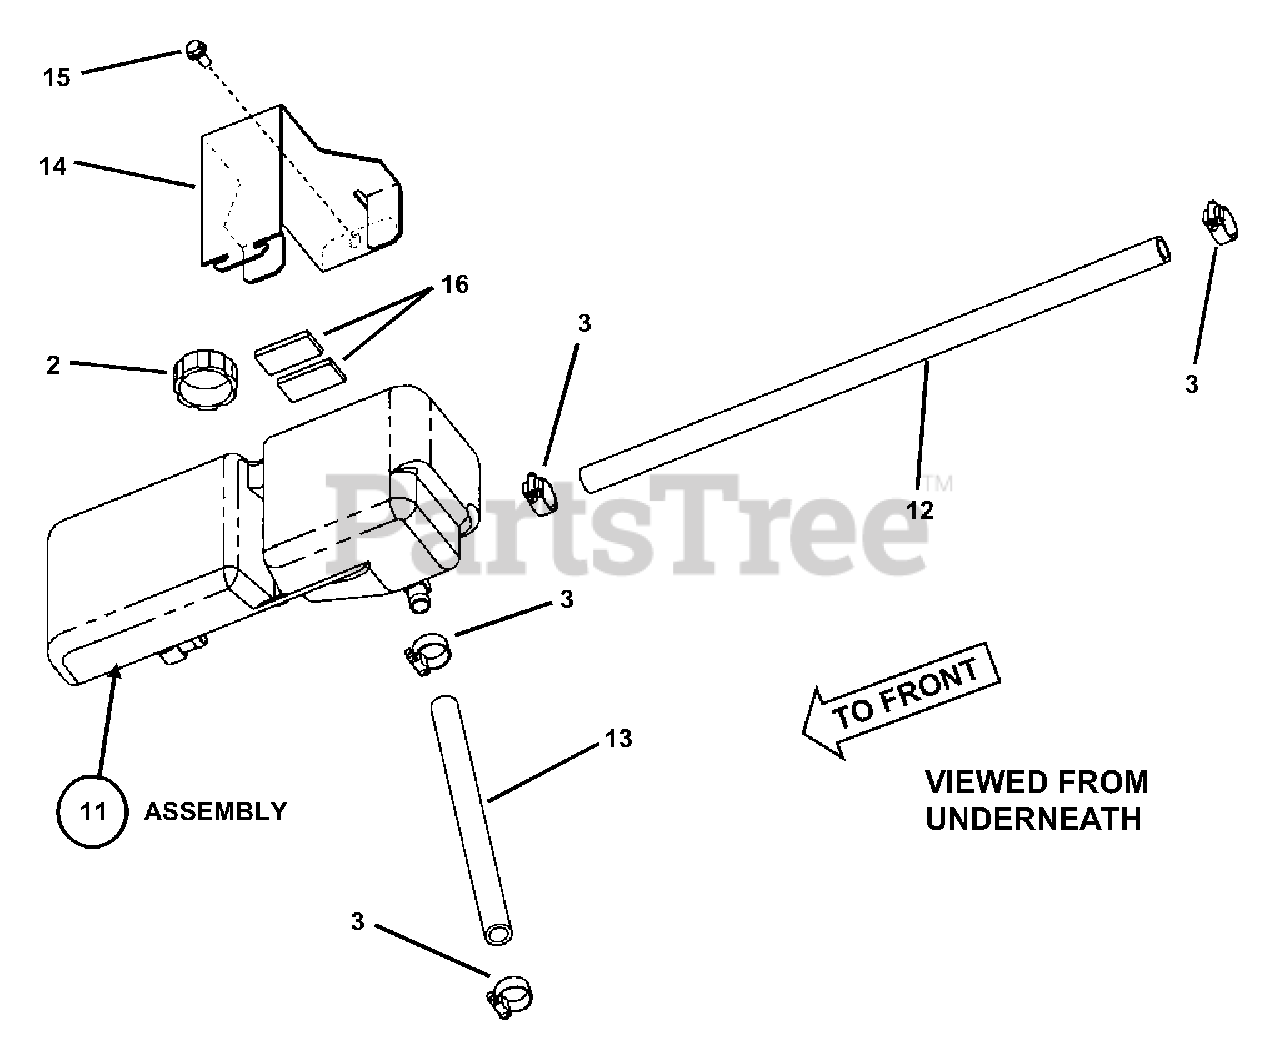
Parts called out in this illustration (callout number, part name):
2	CAP, Reservoir
3	CLAMP,
11	RESERVOIR, (R.H.) Hydro
12	HOSE, Rubber 5/8" I.D. 32" Long
13	HOSE, Rubber 5/8" I.D. 12" Long
14	BRACKET, Tank, (Right Hand)
15	SCREW, 5/16-18 x 5/8" Hex Washer Self-Tap
16	PAD, Gas Tank
